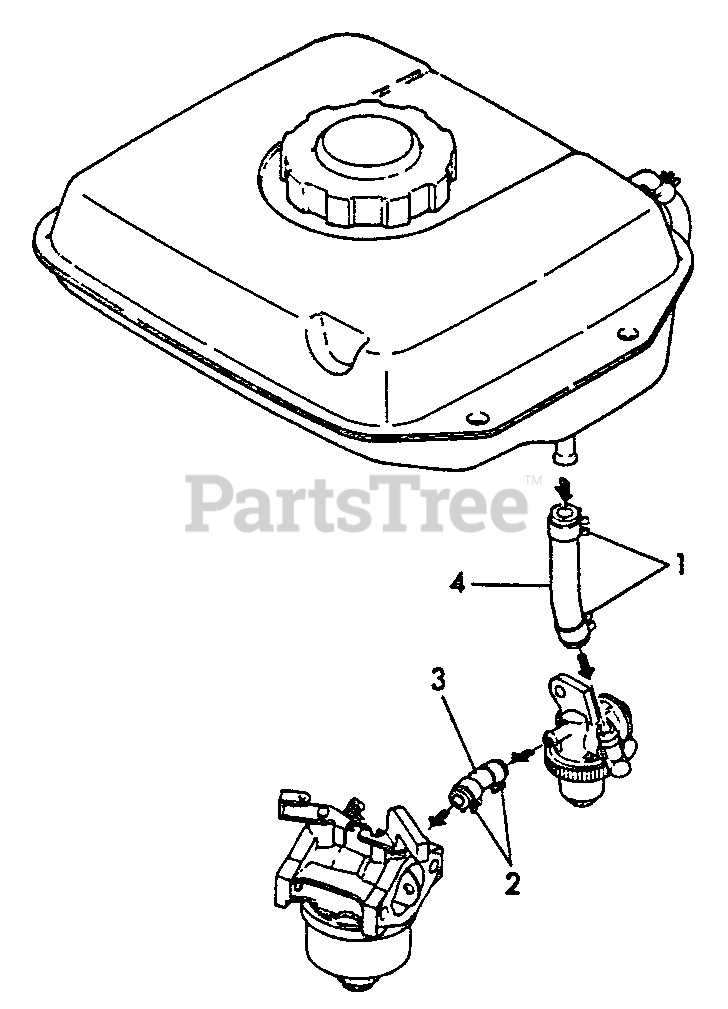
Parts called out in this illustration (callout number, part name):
1	CLAMP, HOSE
2	CLAMP, HOSE - 9
3	PIPE - FUEL
4	PIPE - FUEL
